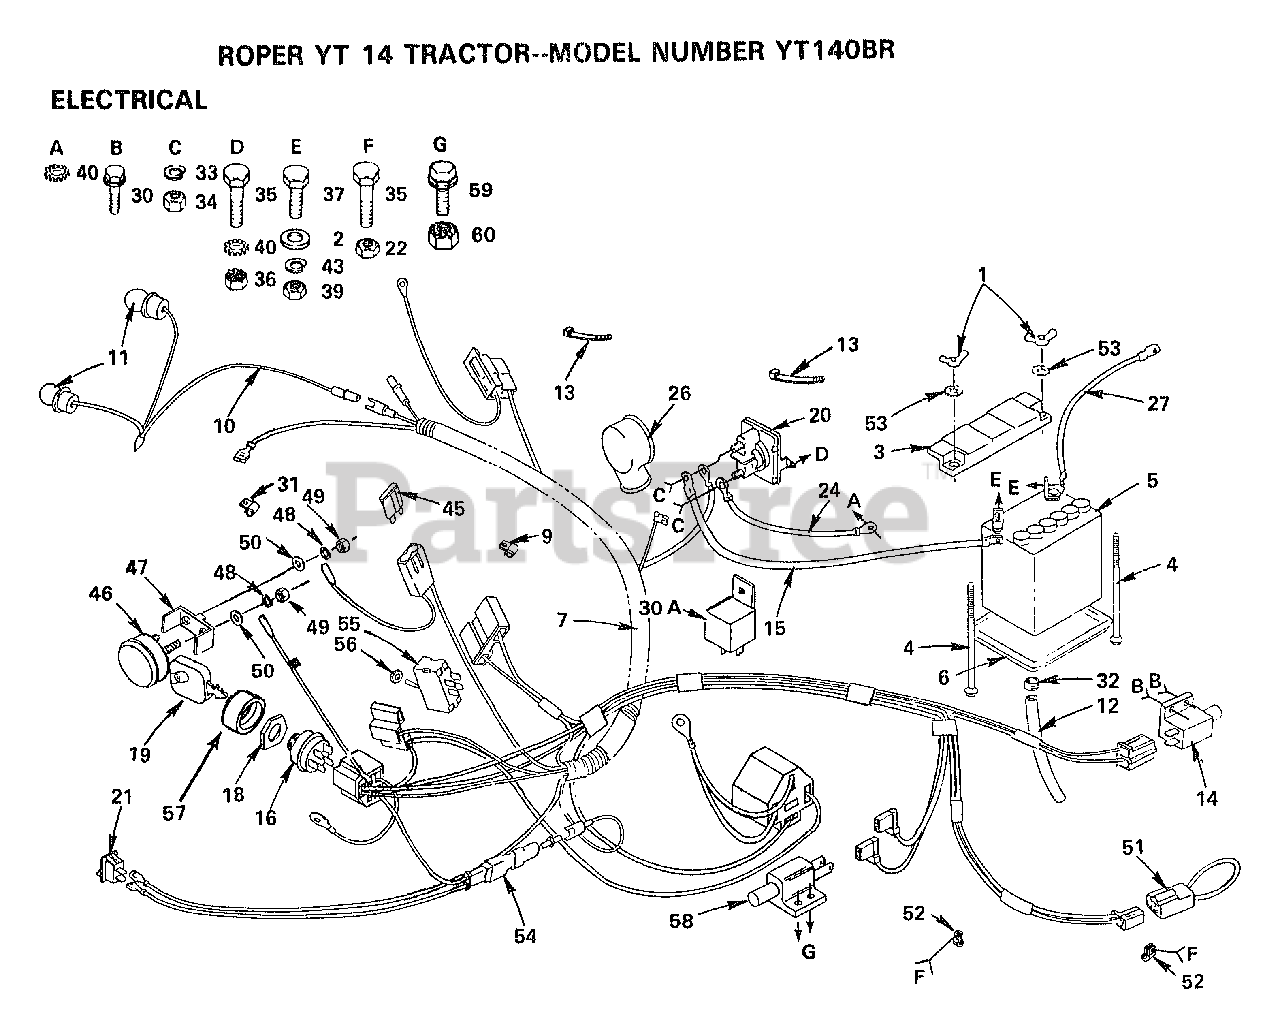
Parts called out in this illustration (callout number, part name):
2	WASHER
4	BOLT
6	"TRAY T, BATTERY"
10	HARNESS T
13	WIRE TIE
14	SWITCH-INTER. GT
15	CABLE-BATTERY T
27	CABLE T
30	SCREW
30A	RELAY ASSY T
31	CLIP T
32	HOSE CLAMP T
34	NUT
35	BOLT
36	NUT
43	LOCKWASHER
45	FUSE HYT
46	AMMETER T
50	WASHER
52	CLIPT
53	LOCKWASHER GT
55	SWITCH.PTO.T
56	HEX NUT T
58	SWITCH T
59	SCREW
60	"NUT,KEPS"
